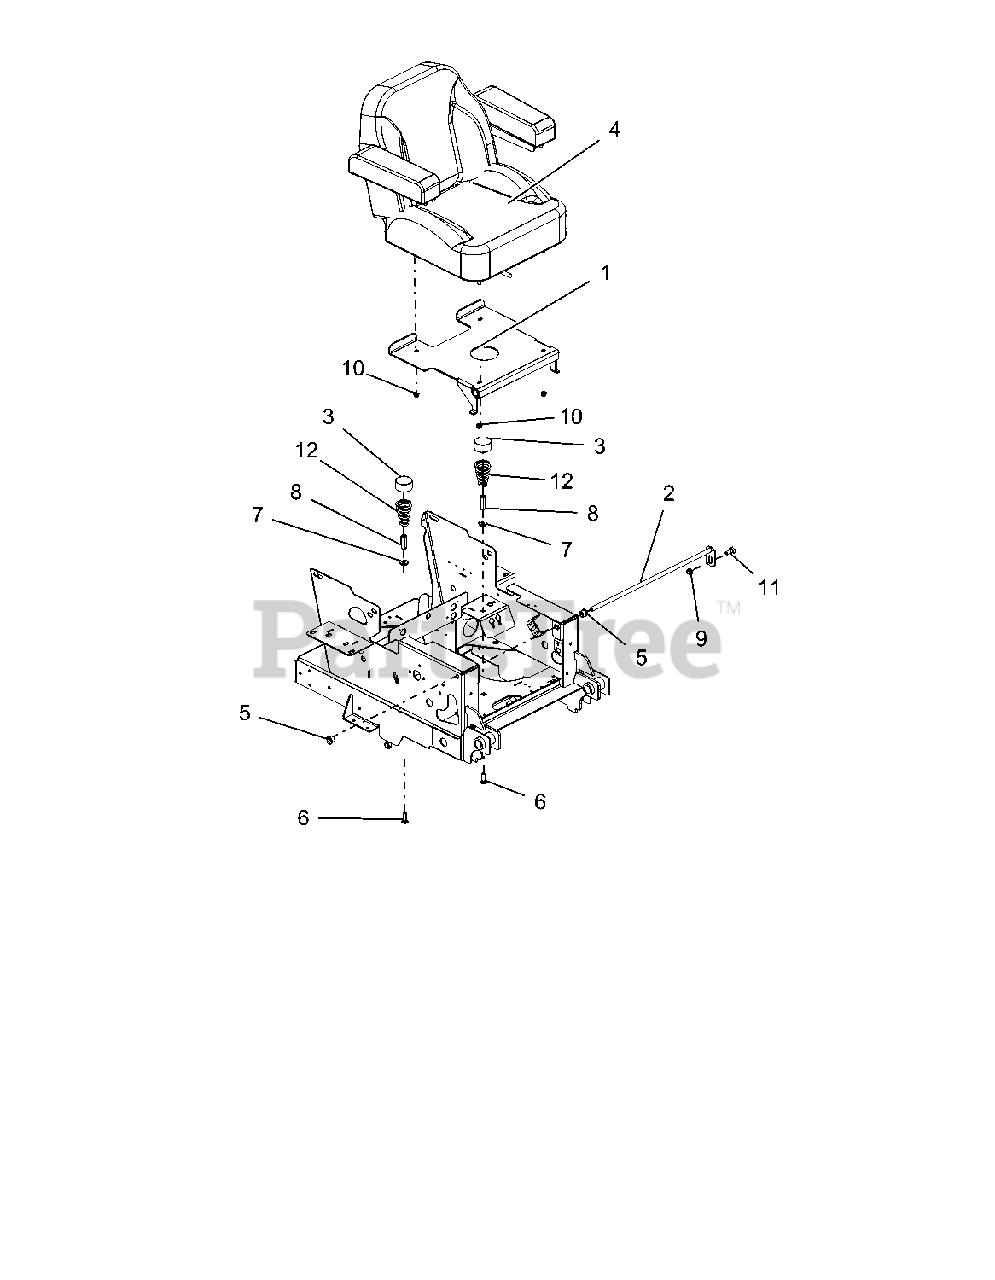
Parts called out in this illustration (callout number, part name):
2	WLDMT, SEAT SHAFT
4	SEAT, SK250 COOL GRAY W/ARMS
5	BSHG, SHLDR EP .358-16X.30 HEX YZ
6	BLT-RDHDSQNK .38-16X1.25 G5 YWZC
7	WSHR-FL-STL .406X1.00X.188 YWZC
8	NUT-HEX COUPLING
9	@NUT-SPNLK-FLG .375-16 YWZC
10	NUT-LK-NYL-FLG .31-18 YWZC
11	BLT, SHLDR EP .38-16X.30 HEX YZ
12	SPRG, COMPRESSION
13	KIT - LH & RH ARM REST REPLACE
